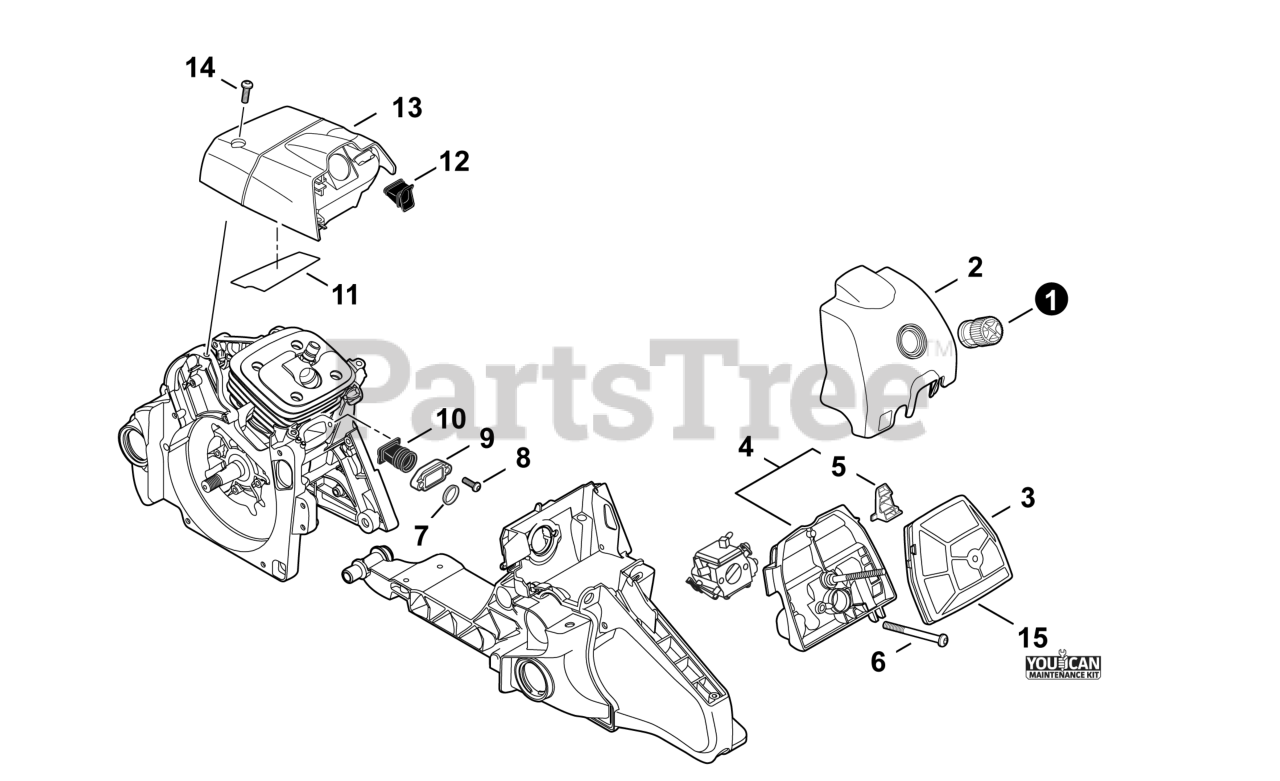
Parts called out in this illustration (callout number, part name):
1	KNOB, AIR FILTER COVER
2	COVER, AIR FILTER
3	FILTER ASSY, AIR
4	CASE, AIR FILTER
5	SHUTTER, AIR
6	BOLT, TORX 5x50
7	COLLAR 18.6x20.4x4
8	BOLT, TORX 5x16
9	HOLDER, BELLOWS
10	BELLOWS, INTAKE
11	SHIELD, HEAT 75x32x0.15
12	PIPE, INTAKE
13	COVER, ENGINE
14	BOLT, TORX 5x16
15	TUNE-UP KIT - YOUCANT
